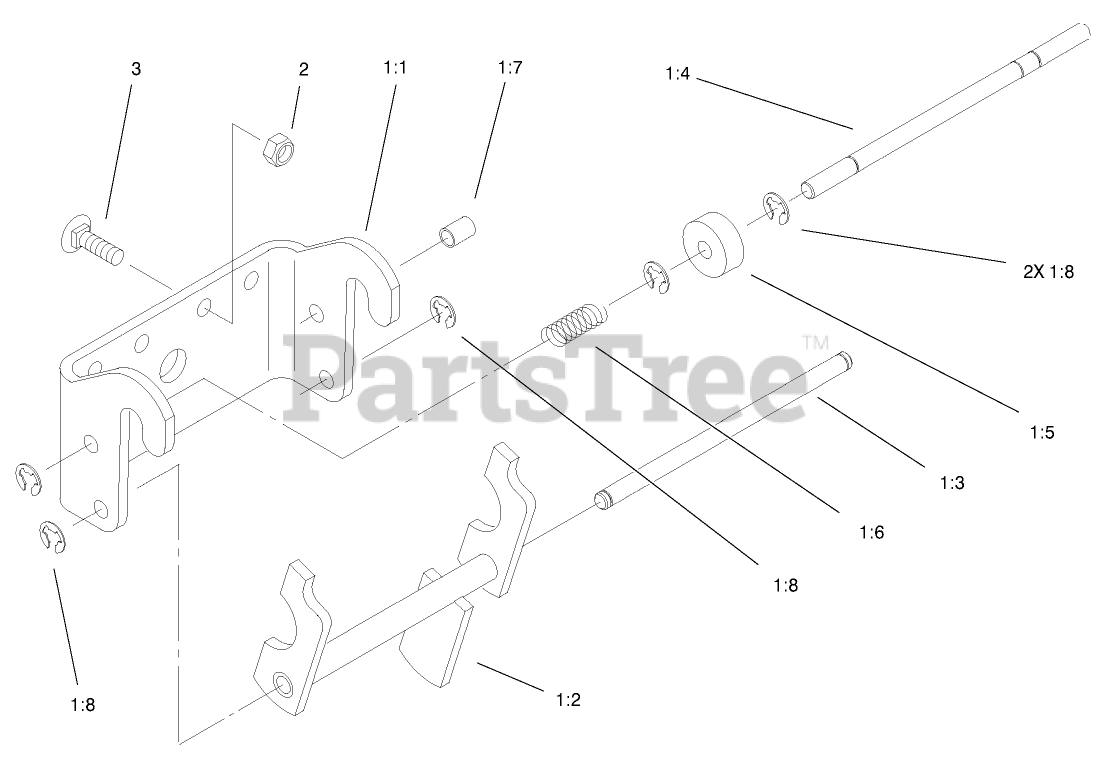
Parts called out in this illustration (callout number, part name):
1:1	HITCH-FRONT
1:2	LATCH
1:3	ROD-LATCH PIVOT
1:4	ROD-LOCK
1:6	SPRING
1:7	CAP-ROD, PLUNGER
1:8	RING-RETAINING
2	NUT-LOCK, NI
3	SCREW-CARR
